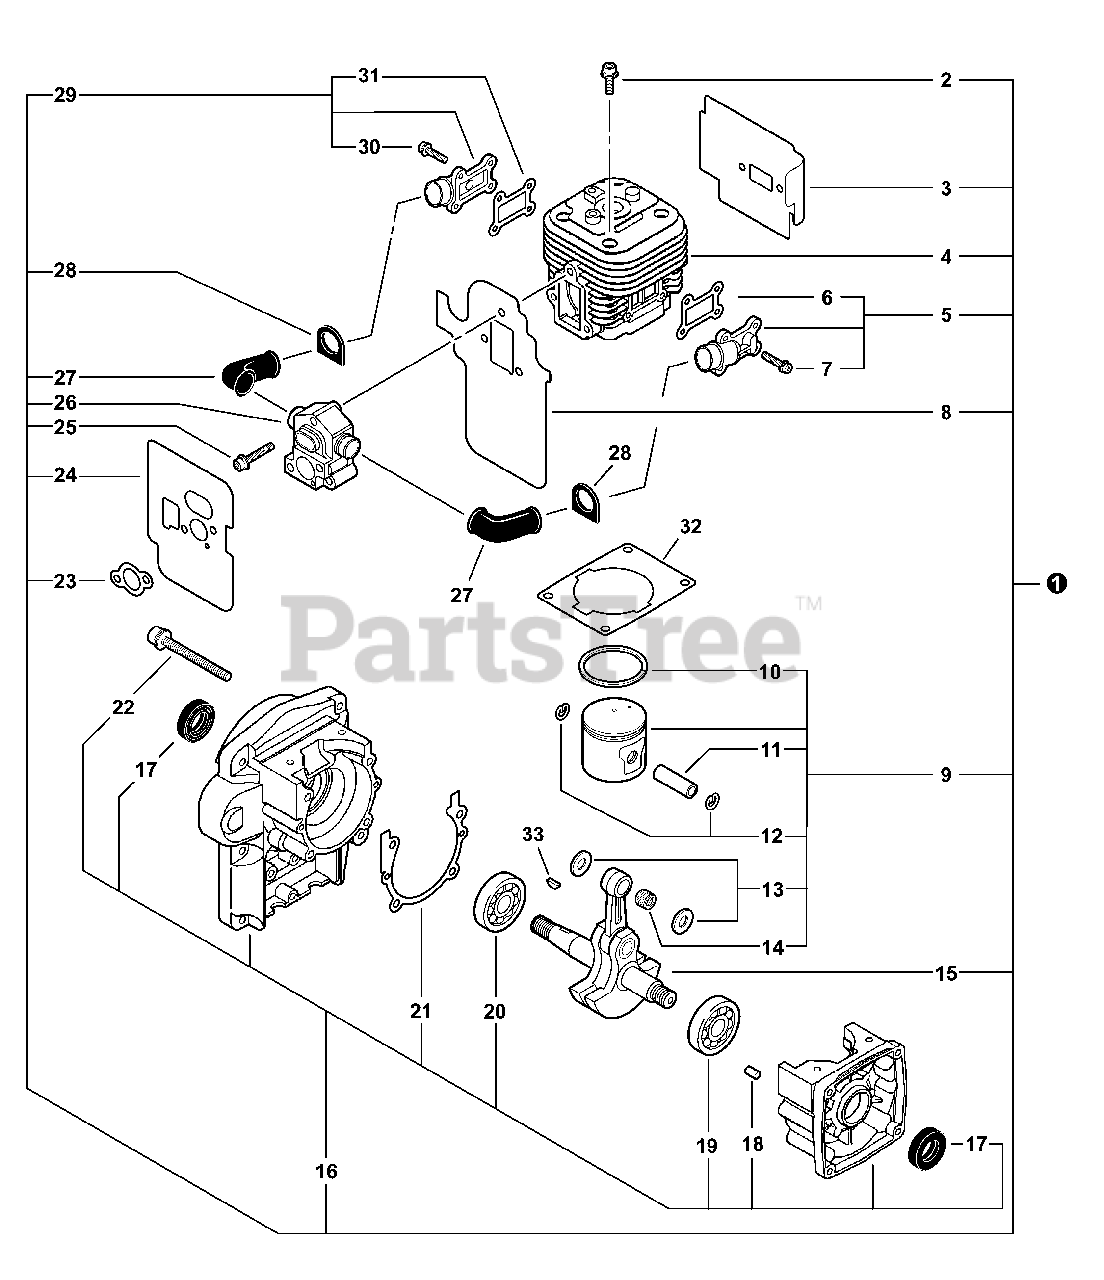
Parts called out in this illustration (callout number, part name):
1	SHORT BLOCK
2	BOLT 5×22
3	HEAT SHIELD, EXHAUST
4	CYLINDER
5	REED VALVE KIT (S)
6	GASKET, INTAKE
8	GASKET, INTAKE
9	PISTON KIT
10	RING, PISTON
11	PIN, PISTON
12	RING, SNAP Ø10
13	WASHER, THRUST 10
14	BEARING, NEEDLE 10
15	CRANKSHAFT ASSY
16	CRANKCASE ASSY
17	SEAL, OIL
18	PIN, LOCATING 4×8
19	BEARING, BALL 6202
20	BEARING, BALL 6302 C3
21	GASKET, CRANKCASE
22	BOLT 5×40
23	GASKET, INTAKE
24	GASKET, INTAKE
26	INSULATOR
27	HOSE, AIR
28	GROMMET
29	REED VALVE KIT (M)
31	GASKET, INTAKE
32	GASKET, CYLINDER
33	KEY, WOODRUFF 3×14
